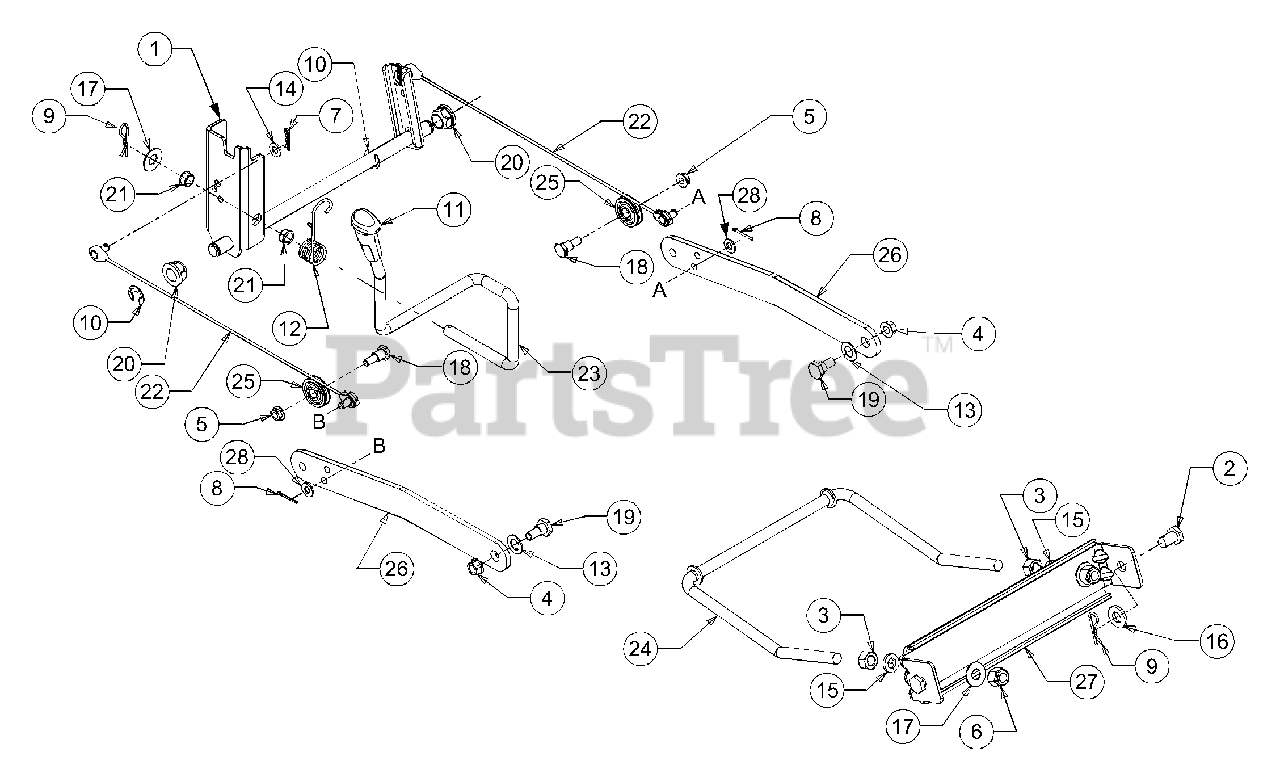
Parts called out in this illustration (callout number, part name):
2	Pin, Clevis, .50 Dia x .78 Lg
3	Nut, Hex, 1/2-13, Gr5
4	Nut, Flange Lock, 3/8-16
5	Nut, Flange Lock, 5/16-18, Gr5
6	Nut, Hex Lock, 1/2-13, Gr8, Nylon
7	Pin, Cotter, .072 Dia. x 1.13 Lg
8	Pin, Cotter, 3/32, 1.0
9	Pin, Click, .092 x 1.64 Lg
10	E-ring, .625 Dia. Shaft
11	Grip, Handle
12	Spring, Torsion
13	Washer, Flat, .53 x .93 x .050
14	Washer, Flat, .344 x .688 x .065
15	Washer, Lock, 1/2 , Regular Duty
16	Washer, Flat, .531 x 1.062 x .134
17	Washer, Flat, .510 x 1.120 x .060
18	Screw, Hex Cap, 5/16-18x.620 Gr2
19	Shoulder Screw, 3/8-16
20	Bearing, Hex Flange
21	Bearing,Flange, Snap .500 ID
22	Cable, Lift, 16.16 Lg
23	Handle, Lift
24	Rod, Deck, Front Adjustment .5" Dia
25	Pulley, Roller
28	Washer, Flat, .344 x .62
